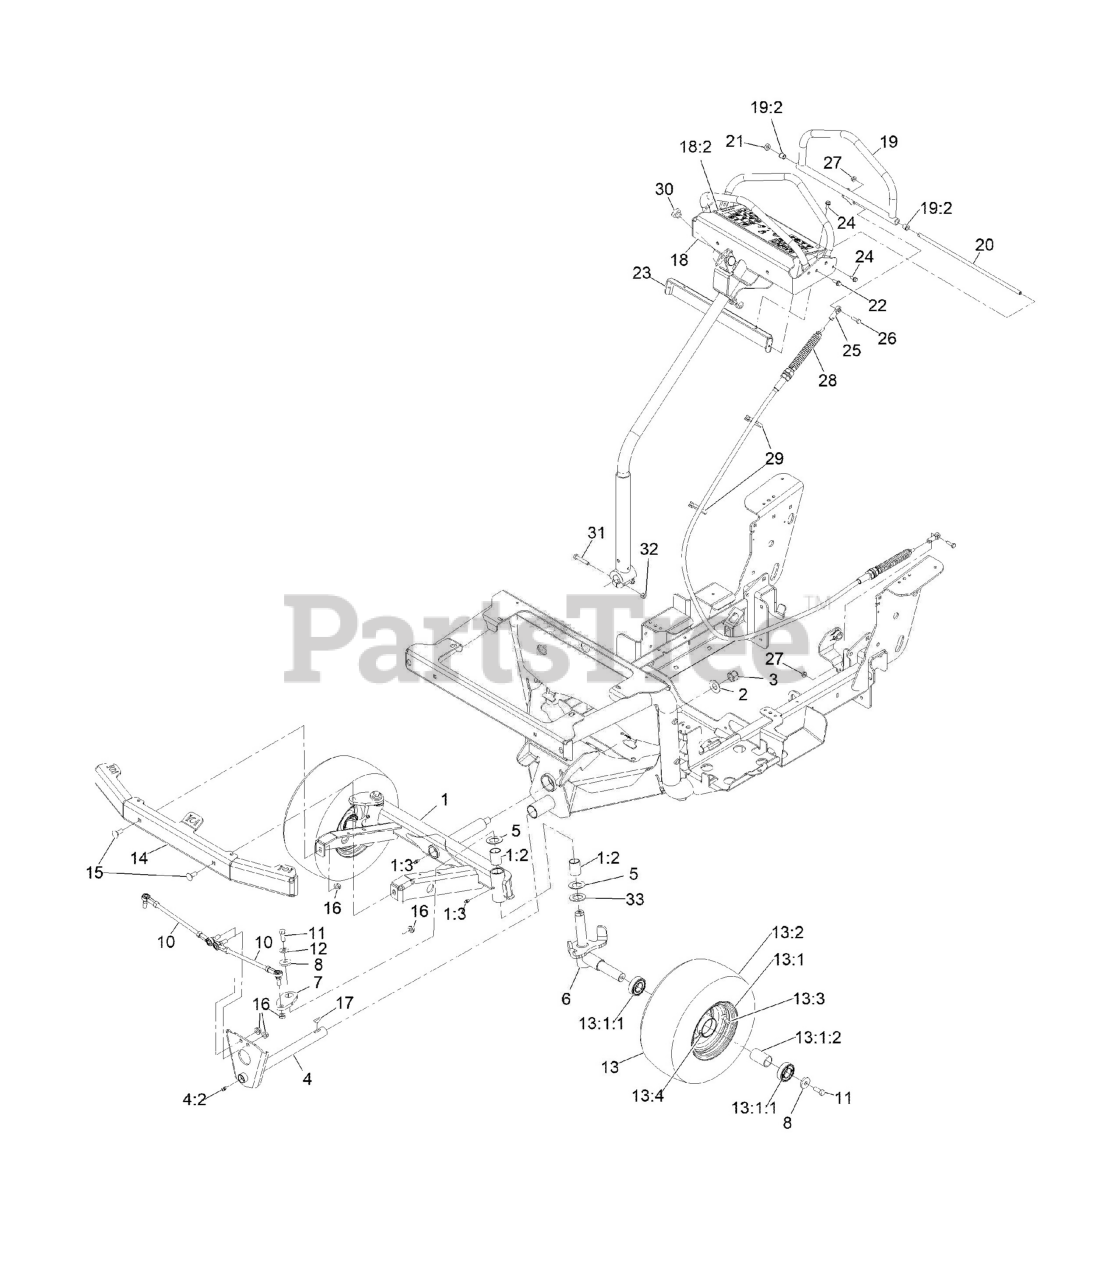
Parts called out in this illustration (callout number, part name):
1	FRONT AXLE ASM
1:2	BEARING-SLEEVE
1:3	ZERK-GREASE
2	WASHER-FLAT
3	NUT-HEX, NI
4	STEERING SHAFT ASM
4:2	ZERK-GREASE
5	WASHER-THRUST
6	FRONT AXLE ASM
7	ARM-STEERING
10	STEERING LINKAGE ASM
11	SCREW-HH
12	WASHER-BELLEVILLE
13	Wheel And Tire ASM
13:1	Wheel ASM
13:1:1	BEARING-BALL
13:3	Stem-Valve
13:4	FITTING-GREASE
14	BUMPER-FRONT
15	SCREW-CARR
17	KEY-WOODRUFF
18	Motion Handle ASM
18:2	DECAL-WARNING
19	Motion Handle ASM
19:2	BEARING
20	SHAFT-PIVOT, SPEED CONTRO
21	SPACER-SHAFT, DRIVE LEVER
22	SCREW-HHF
23	PANEL-REAR, STEERING
24	SCREW-HWH
25	ROD END-BALL JOINT
26	SCREW-HH
28	CABLE-MOTION
29	TIE-CABLE
30	BUMPER-RUBBER
31	Screw-HH
32	NUT-HEX
33	SPACER-RELIEF
